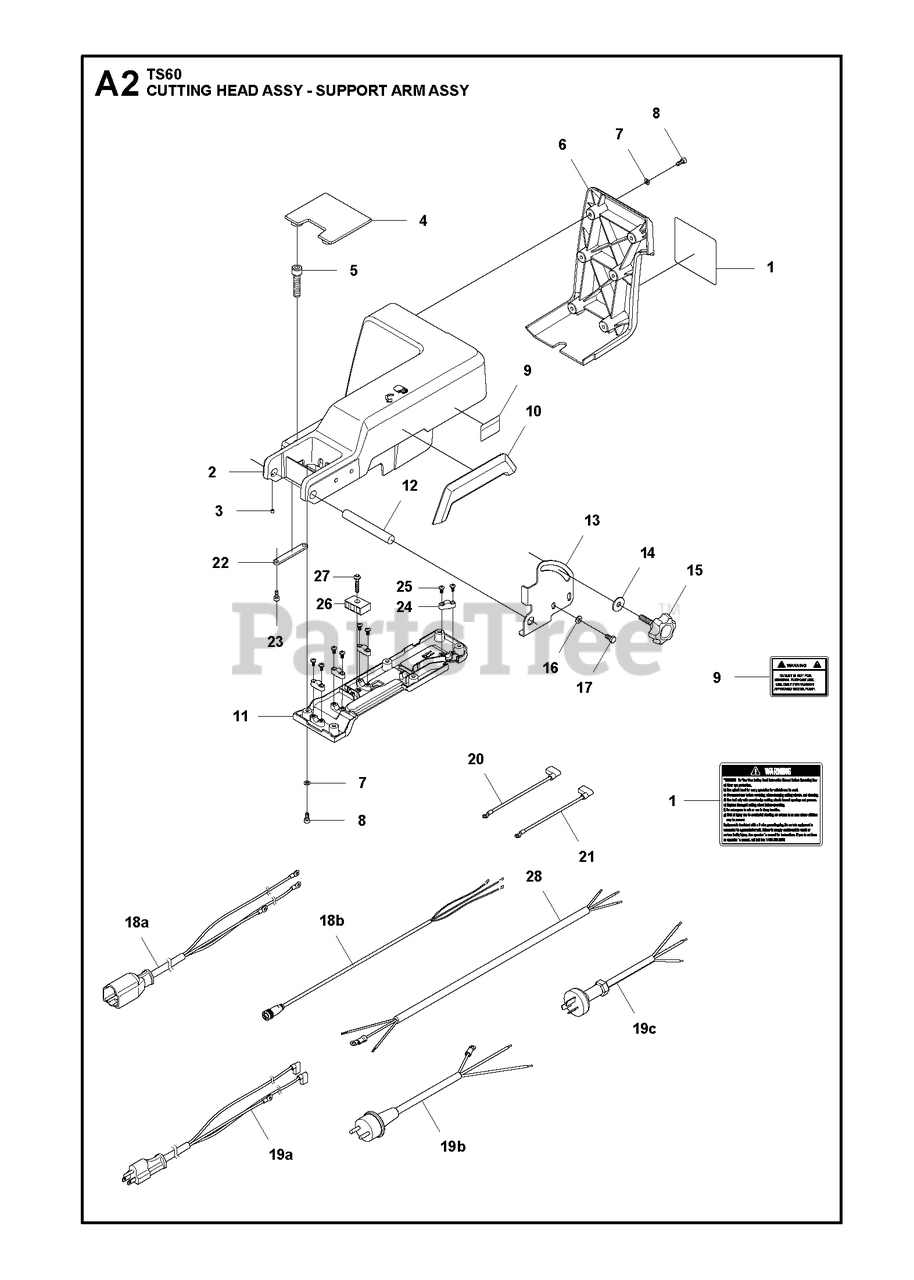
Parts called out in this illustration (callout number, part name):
3	SCREW IHSETM
7	WASHER
24	CABLE CLAMP230V
25	SCREW CCRPANT230V
